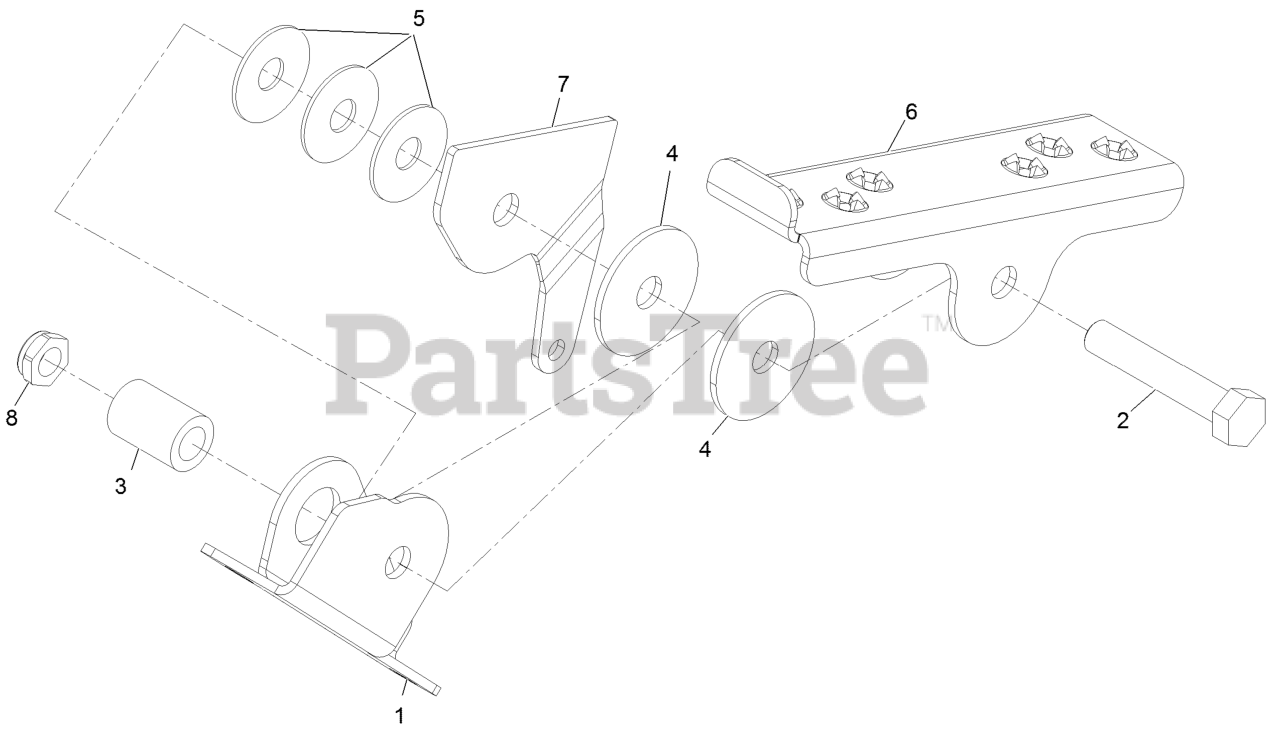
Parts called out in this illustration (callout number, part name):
1	BRACKET-PEDAL MOUNT
2	SCREW-HH
3	SPACER-ROLLER
4	DISC-FRICTION
5	WASHER-DISC, SPRING
6	CHANNEL,PEDAL LINK
7	ARM, FOOT PEDAL
8	NUT-HEX
